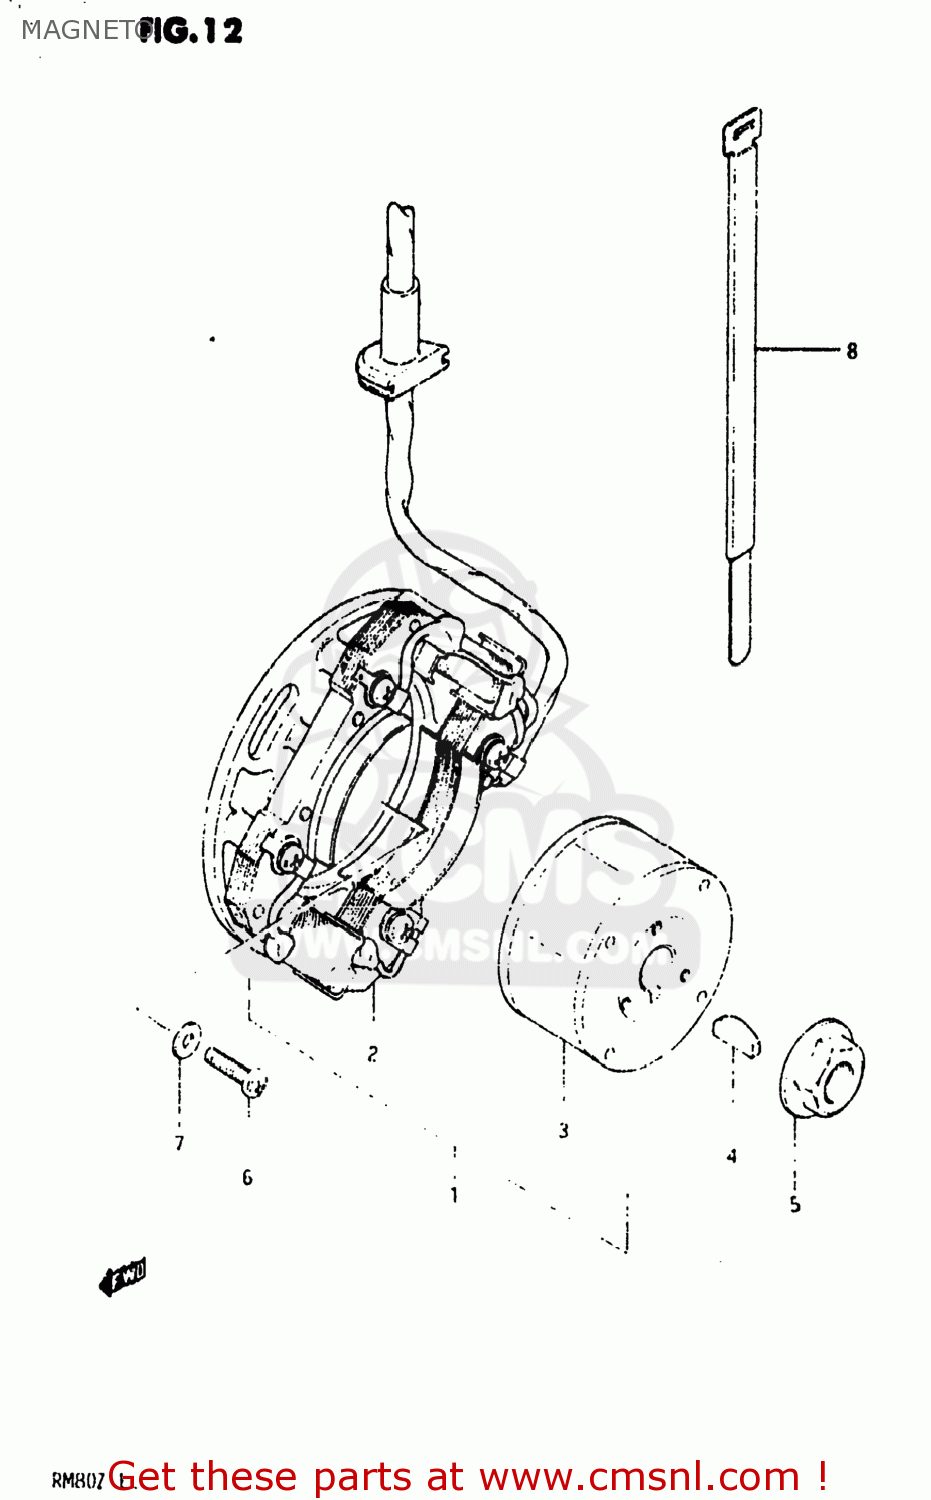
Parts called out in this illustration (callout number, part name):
1	MAGNETO ASSEMBLY
2	STATOR ASSEMBLY
3	ROTOR ASSEMBLY
4	KEY 4MM
5	NUT
6	SCREW
7	WASHER
8	CLAMP
